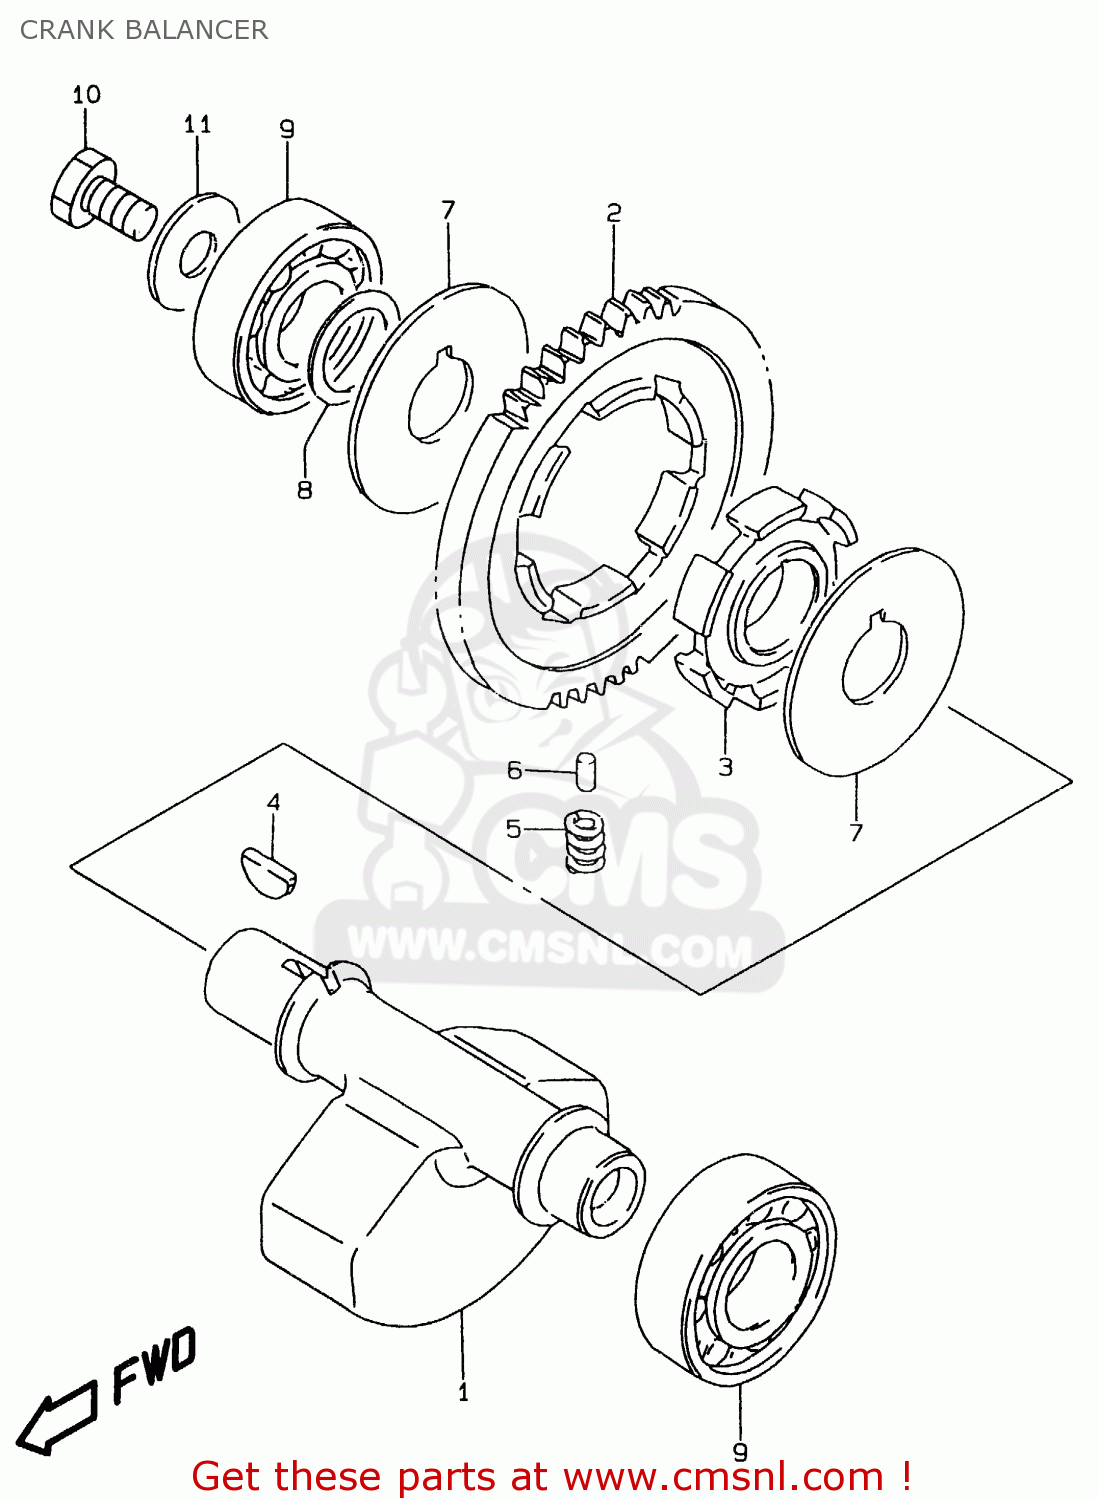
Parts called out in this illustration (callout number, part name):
1	SHAFT,CRANK BALANCER
2	GEAR,CRANK BALANCER DRIVEN
3	RACE,CRK BAL DRIVEN GEAR INNER
4	KEY
5	SPRING
6	PIN(4.5X9.5)
7	WASHER
8	THRUST WASHER
9	BEARING(20X47X14)
10	BOLT
11	WASHER
